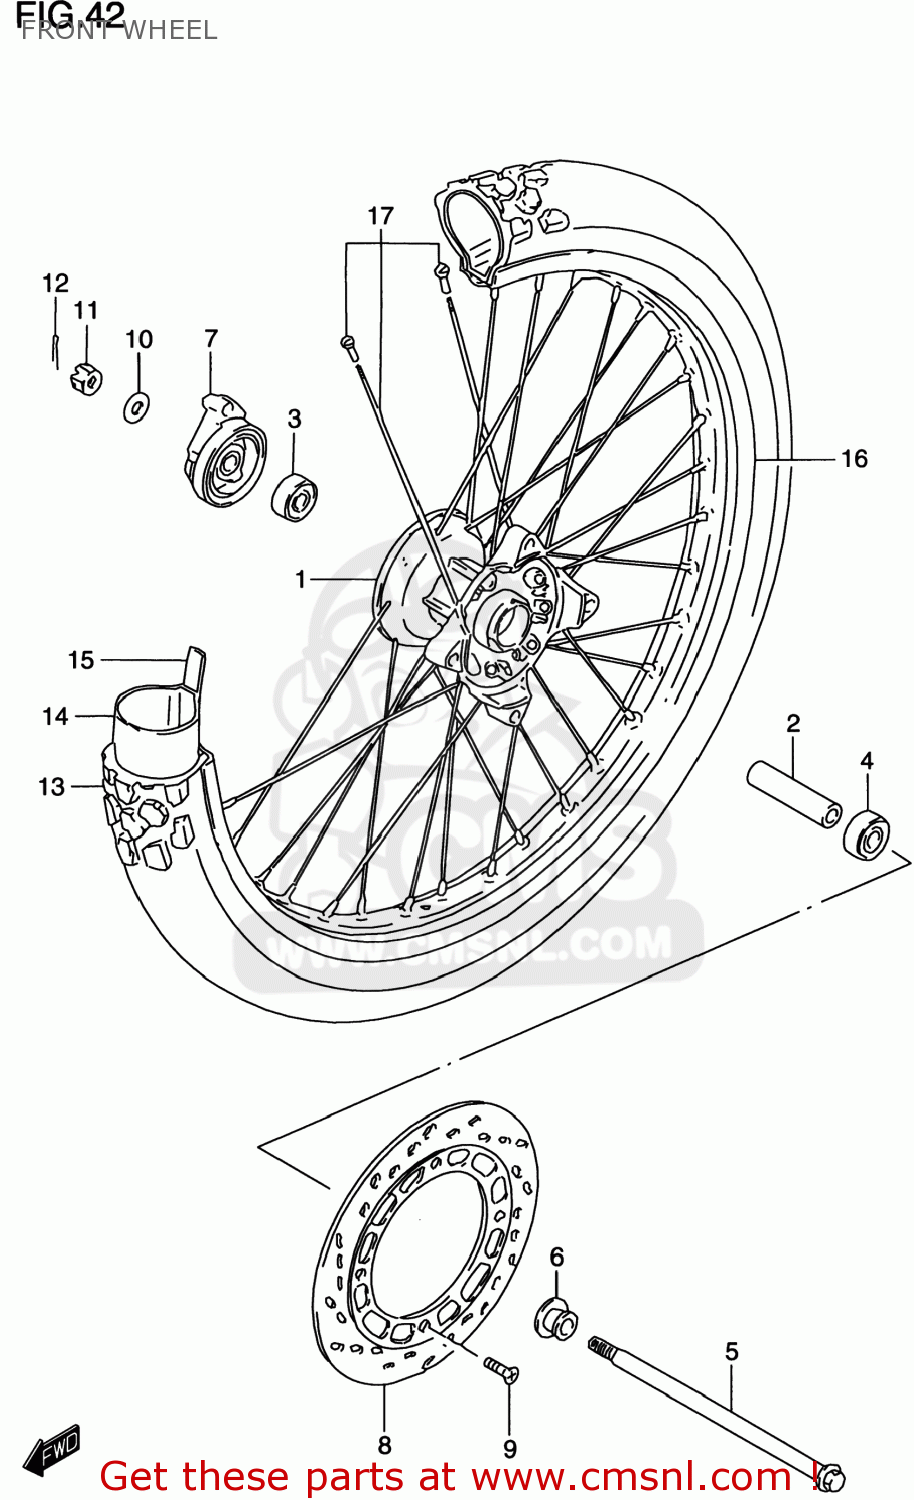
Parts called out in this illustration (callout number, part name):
1	HUB,FR WHEEL
2	SPACER(12.5X19X60.5)
3	BEARING
4	BEARING (12X32X10)
5	AXLE,FR
6	SPACER,FR AXLE
7	BOX ASSY,SPEEDOMETER GEAR
8	DISC,FR BRAKE
9	BOLT,BRAKE DISC
10	WASHER
11	NUT
12	COTTER PIN
13	TIRE,FR(70/100-21 44P)
14	TUBE
15	PROTECTOR,WHEEL INNER
16	RIM,FR WHEEL(21X1.60)
17	SPOKE SET,FR WHEEL
